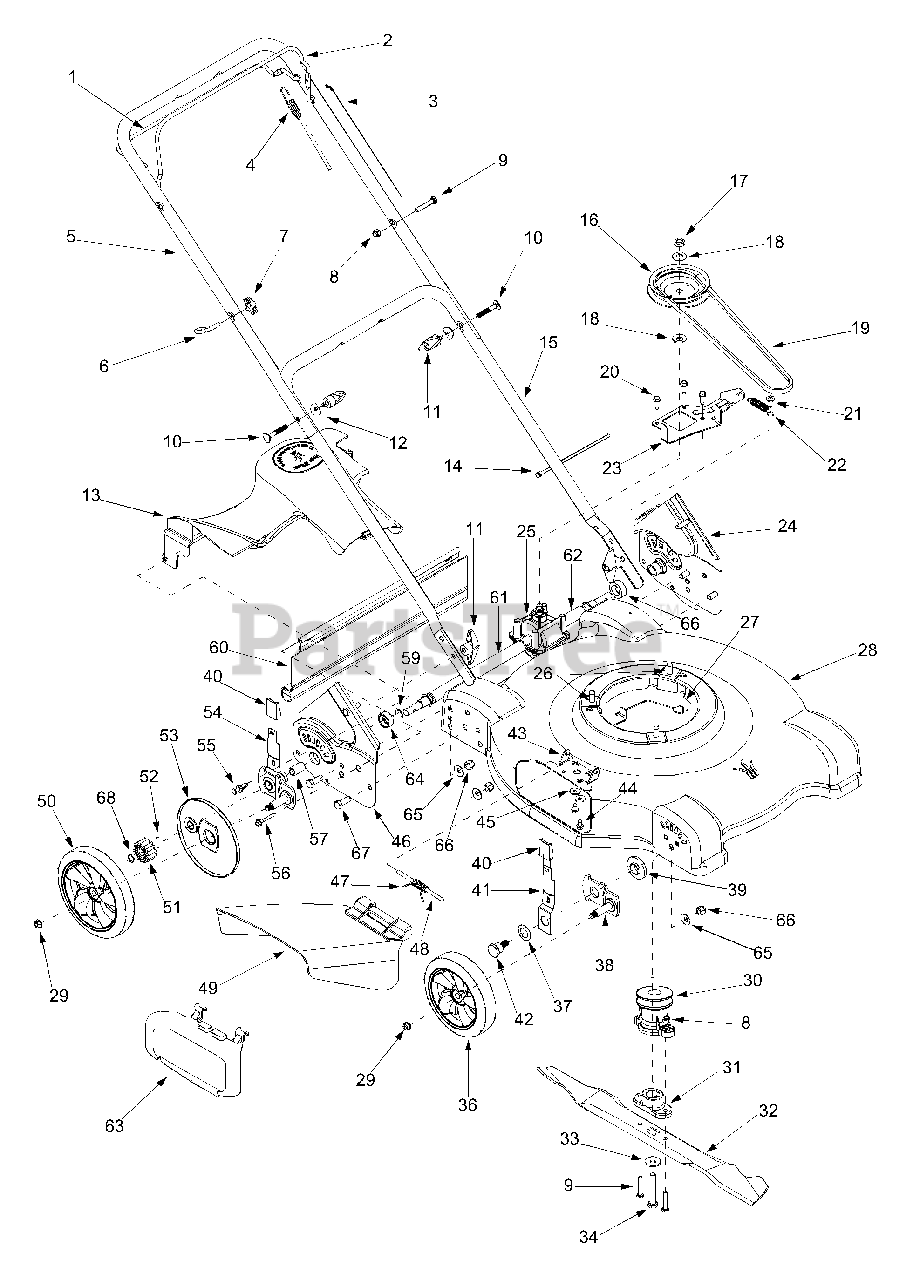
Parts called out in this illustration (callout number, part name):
1	Drive Control Handle
3	Blade Control Cable - B&S (37.75")
3	Blade Control Cable - B&S (40.75")
3	Blade Control Cable - Tec (50.5")
4	Drive Control Cable
6	Eye Bolt
7	Wing Nut 1/4-20
8	Hex Lock Nut 1/4-20
9	Hex Cap Screw 1/4-20 x 1.5
10	Carriage Bolt 5/16-18 x 2.0
11	Wing Nut 5/16-18
12	Shoulder Washer .320 ID x .93 OD
13	Transmission Cover
14	Cable Tie
16	Transmission Pulley
17	Jam Nut 7/16-20
18	Bell Washer .45 ID x 1.00 OD
19	V-Belt
20	Hex Washer Screw 1/4-20 x .75
21	Shoulder Screw .375 x .25
22	Extension Spring
23	Transmission Belt Bracket
26	Hex Washer Screw 3/8-16 x 1.0
27	Engine Belt Keeper Bracket
28	Deck Assembly 22"
28	Deck Assembly 22" (No Sprigs)
29	Flange Lock Nut 3/8-16
30	Blade Adapter, One Piece
32	Blade 22"
32	Mulching Blade 22"
33	Bell Washer .396 ID x 1.140 OD
34	Hex Cap Screw 3/8-24 x 2.5
35	Shoulder Screw 3/8
36	Front Wheel 7 x 1.8
37	Bell Washer .401 ID x .870 OD
38	Pivot Arm Assembly
39	Height Adjuster Bearing
40	Height Knob
41	Spring Lever
42	Shoulder Screw 3/8-16
43	Chute Hinge
44	Hex Washer Screw 1/4-20 x .50
45	Bell Washer .265 ID x .75 OD
48	Hinge Pin
49	Side Discharge Assembly
50	Rear Wheel 8 x 1.8
51	Spur Gear 14T RH
51	Spur Gear 14T LH
52	Pin
53	Wheel Cover
54	Spring Lever Assembly - RH* (RWD)
54	Spring Lever Assembly - LH* (RWD)
55	Plastic Rivet
56	Screw 1/4-20
57	Sleeve Bearing
58	Hex Cap Screw 3/8-16 x .75
59	Retainer Ring
60	Trail Shield
61	Sleeve Spacer .550 ID x 9.0 OD
62	Sleeve Spacer .550 ID x 2.44 OD
63	Snap Mulching Plug
64	Bearing Spacer
65	Washer Spacer .401 ID x .870 OD
66	Hex Lock Nut 3/8-16
67	Hex Cap Screw 3/8-16 x 1.0
68	Snap Ring .500
